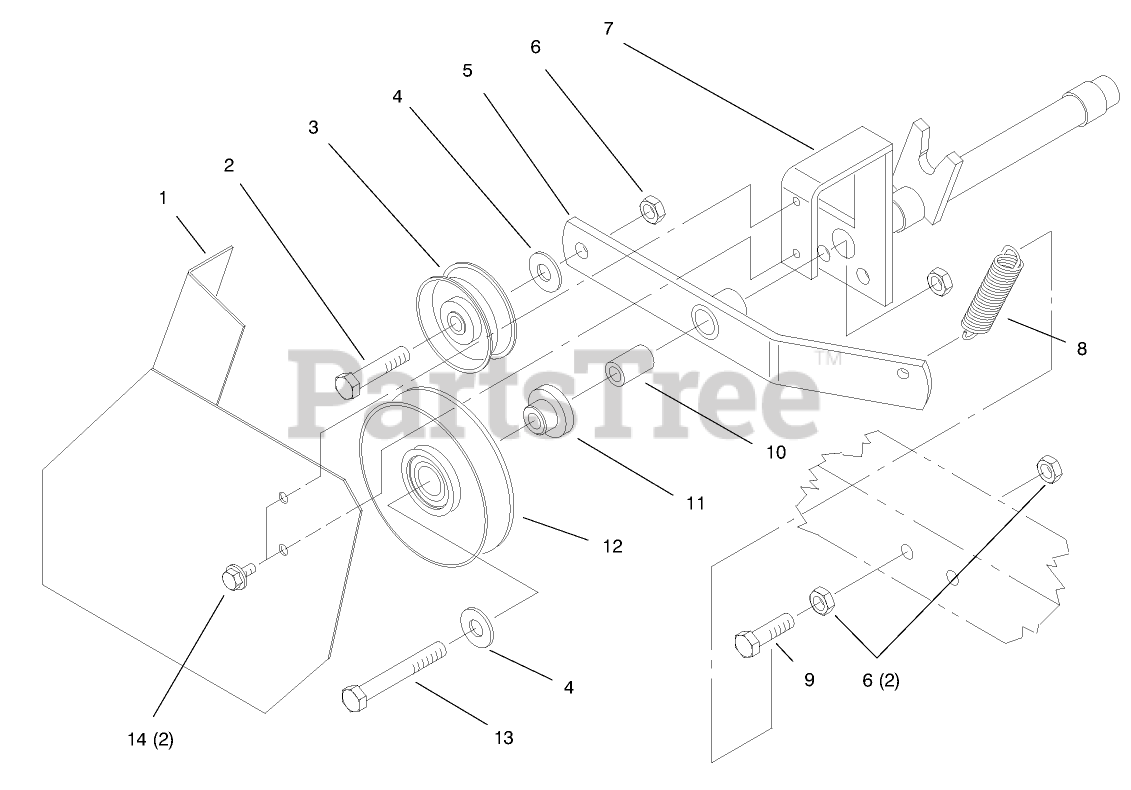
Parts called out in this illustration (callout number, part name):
2	SCREW-HH
3	IDLER PULLEY
4	WASHER-FLAT
8	SPRING-BRAKE
9	SCREW-HH
10	SPACER
11	SPACER
12	PULLEY-IDLER
13	SCREW-HH
14	SCREW-HWH
